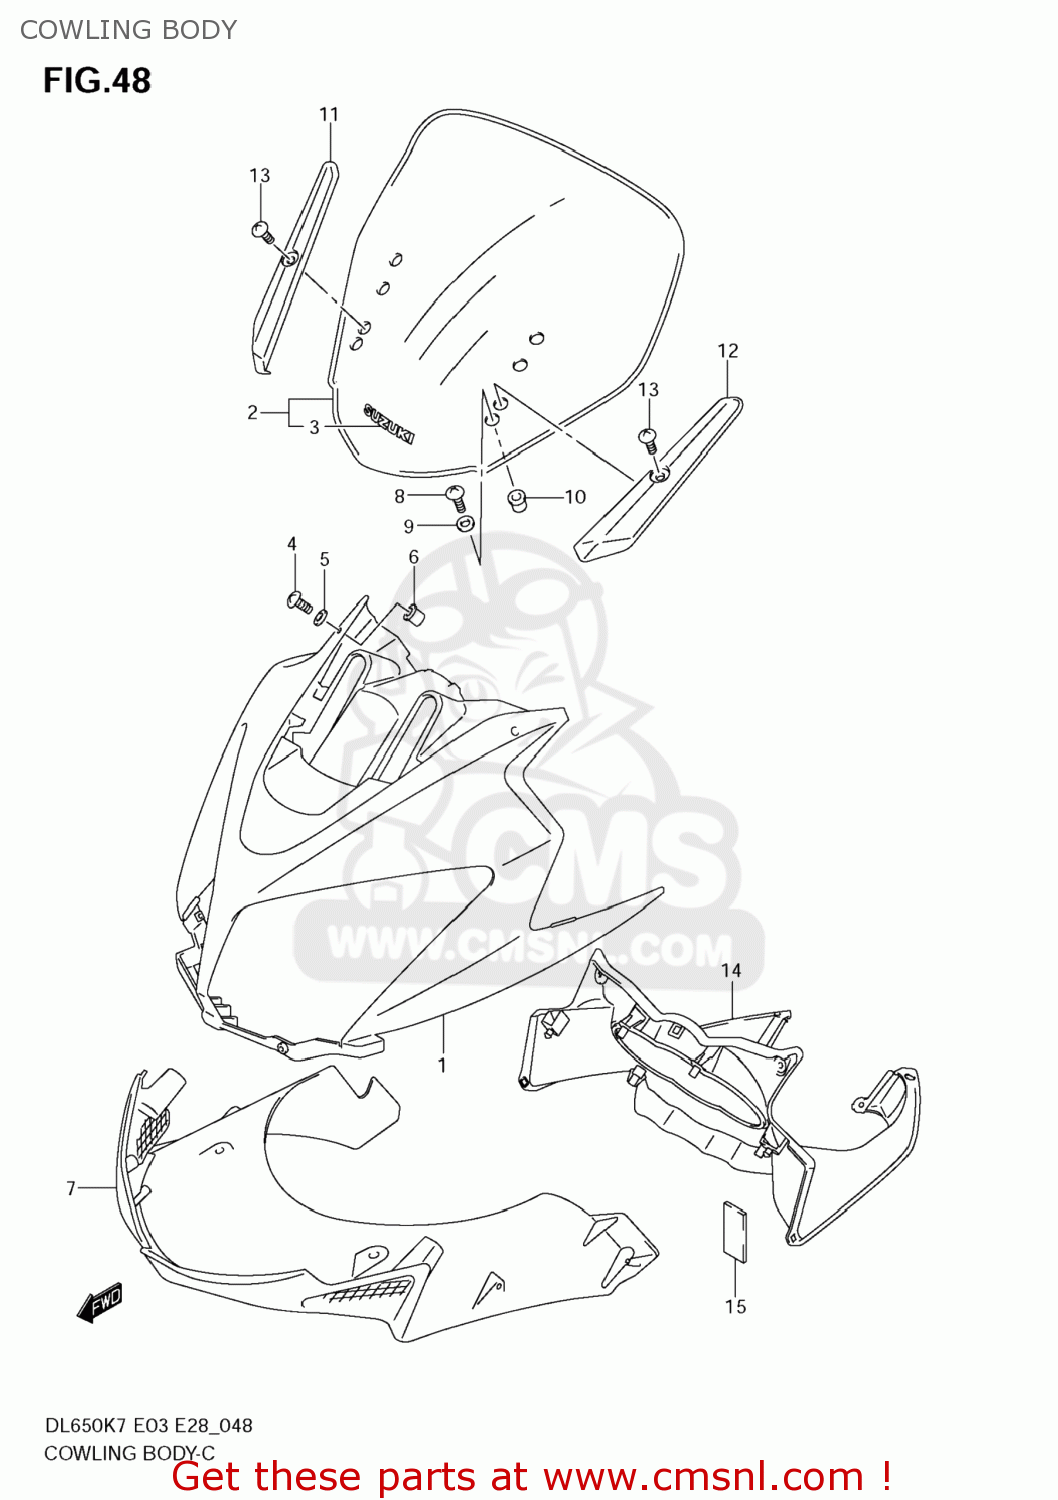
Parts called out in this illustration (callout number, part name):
1	COWLING,BODY(BLACK)
2	WINDSCREEN
3	TAPE,WINDSCREEN
4	SCREW(5X22)
5	WASHER
6	NUT,UNDER COWL BRACE RR
7	COVER,COWLING INNER
8	SCREW
9	WASHER(5.2X14X1.5)
10	NUT
11	COVER ASSY,WINDSCREEN,R
12	COVER ASSY,WINDSCREEN,L
13	SCREW(5X16)
14	PANEL,METER(BLACK)
15	CUSHION
